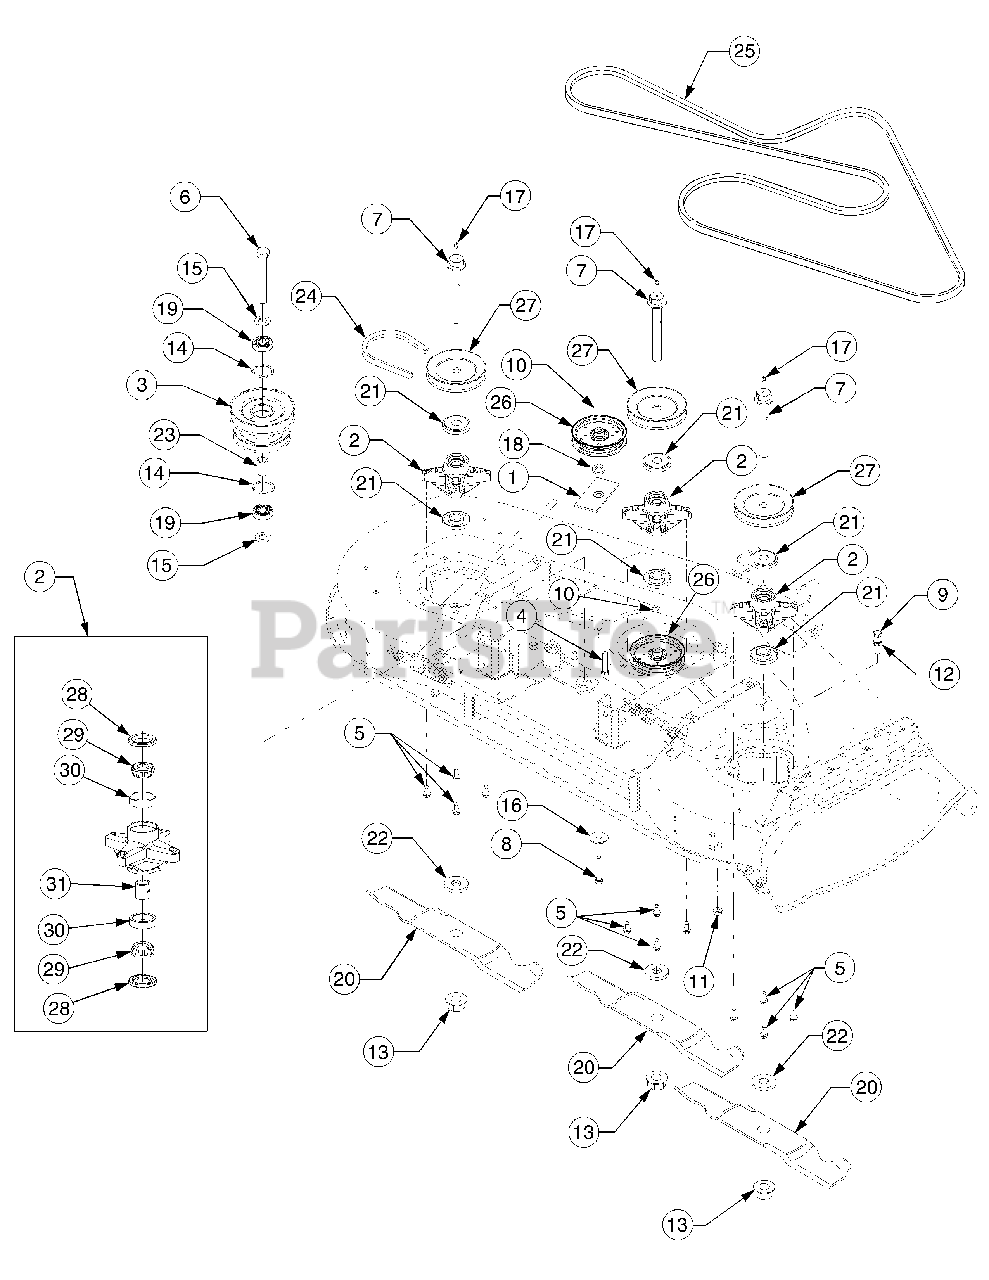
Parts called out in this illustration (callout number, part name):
2	Assembly, Spindle Includes Ref. Nos. 28 thru 31
3	Pulley, Double
4	Screw, Hex Cap 3/8-16 x 1.75 GR5
5	Screw, Hex Wash Hd Tapp
6	Screw, Hex Cap, 5/8-18 x 3 GR5
7	Bolt, Spindle, 3/4-16 x 5.215
8	Screw, Hex Cap 3/8-16 x 2.75 GR8
9	Screw, Hex Cap, 5/16-18 x 2.25 GR5
10	Nut, Flange Lock 3/8-16 GRF
11	Nut, Flange Lock, 5/16-18 GR5
12	Nut, Hex, 5/16-18 GR5
13	Nut, Hex Flange, 3/4-16
14	Ring, Internal Retaining
15	Washer, Flat .65 x 1.25 x .075
16	Washer, Flat .406 x 1.5 x .105
17	Fitting, Grease
18	Spacer, Shoulder
19	Bearing, Ball,
20	Blade, High Lift 18.5" Lg.
20	Blade, Hard Coated
21	Spacer, Deck Spindle
22	Spacer, Blade
23	Spacer, .635 x .88 x 1.25
24	Belt, "V" 114.24" Lg.
25	Belt, "V" 111.4" Lg.
26	Pulley, Flat, 4.25 Dia.
27	Pulley, "V"
28	Seal, Oil, 1.25 x 1.874 x .25
29	Bearing, Cone
30	Cup, Bearing
31	Spacer, Bearing
